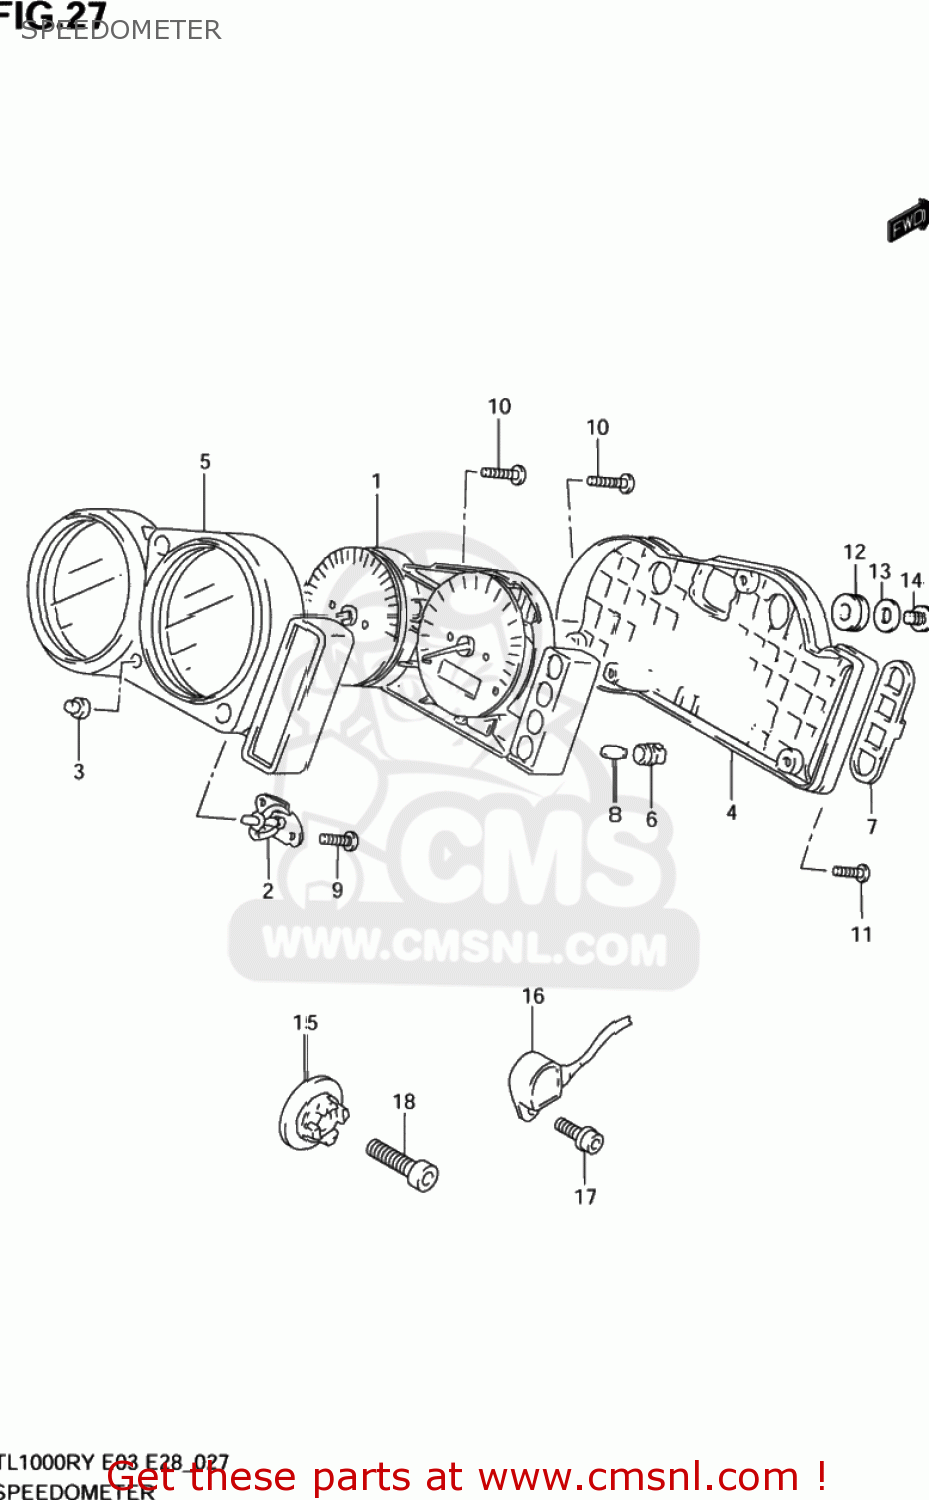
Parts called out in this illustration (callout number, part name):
1	SPEEDOMETER(KILO)
2	ATTACHMENT,SWITCH
3	SWITCH,GUM
4	CASE ASSY
5	VISOR,METER
6	SOCKET(T:6.5)
7	CAP,BLIND NO.2
8	BULB(12V1.7W,T6.5)
9	SCREW(3X10)
10	SCREW
11	SCREW
12	CUSHION,METER
13	WASHER(5.5X16X1.2)
14	SCREW
15	ROTOR,SPEED
16	SENSOR,SPEED
17	BOLT
18	BOLT
